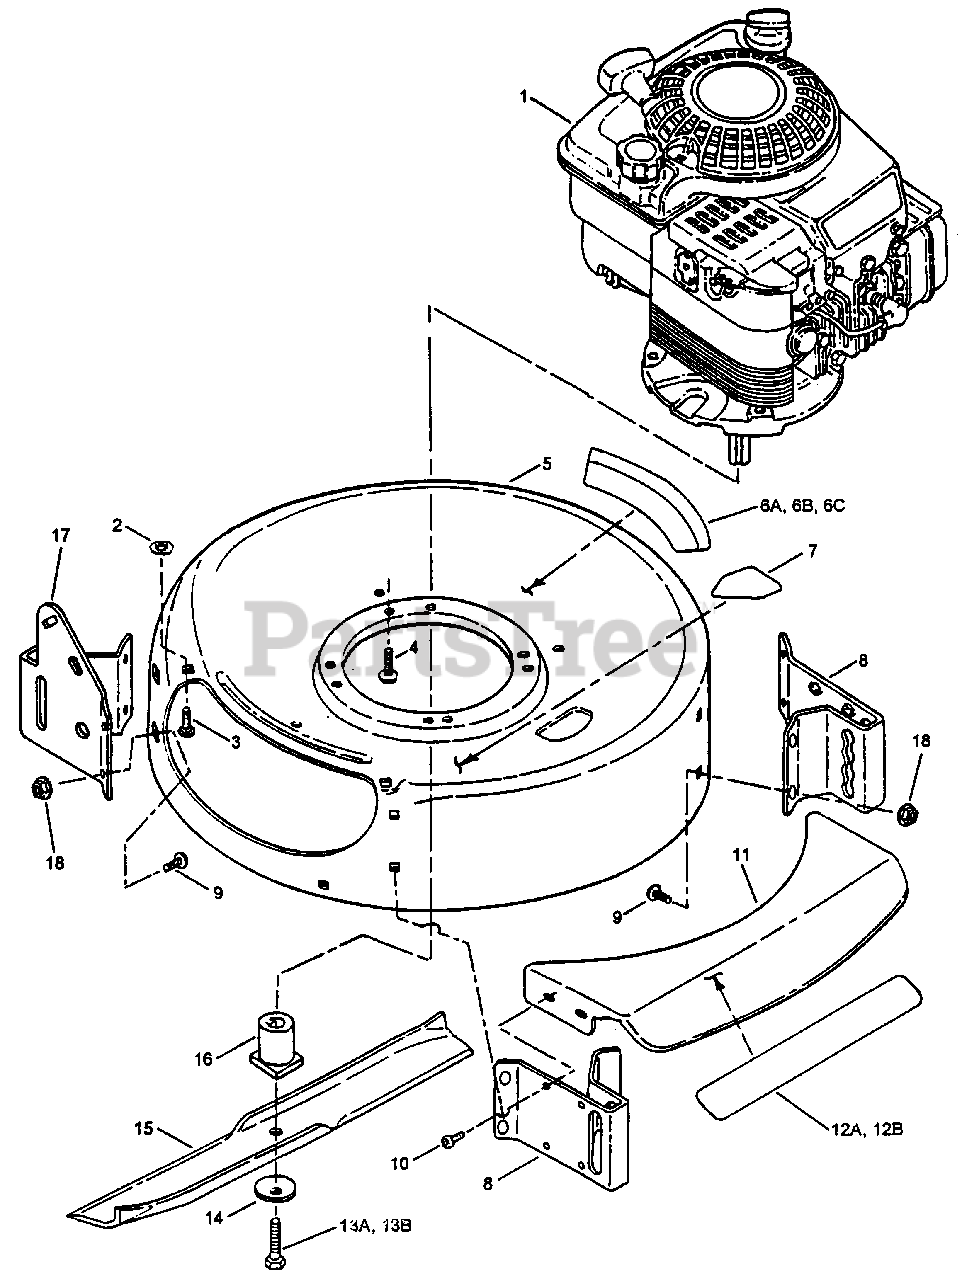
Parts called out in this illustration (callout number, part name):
2	RETAINER, 5/16 Bolt
3	BOLT, 5/16-18 x 3/4 Short Neck Carriage, Grade 5
4	SCREW, 3/8-16 x 1 Hex Washer Head, Self-Tapping
5	DECK, 20" Cutting
6A	DECAL - Feature/Compliance
6B	DECAL, Dura-Steel Convertible/Compliance
6C	DECAL, Warning (Deck)
7	DECAL - DANGER (Keep Hands & Feet Away)
8	BRACKET, Front Wheels
9	BOLT, 5/16-18 x 1/2 Short Neck Carriage, Grade 5
10	SCREW, #10-24 x 1/2" Hex Washer Self-Tap (Torx)
11	PLATE, Deck Front
12A	DECAL, SNAPPER "Lite"
12B	DECAL, Snapper
13A	SCREW, 3/8-24 x 2 Hex Head Cap, Grade 5
13B	SCREW, 3/8-24 x 1-3/4" Hex Head Cap, Grade 5
14	WASHER, Cone
15	BLADE, Mulching
16	HUB, Blade
17	BRACKET, Rear Wheel Right Side
18	NUT, 5/16-18 Hex Flange Lock, Grade 5
